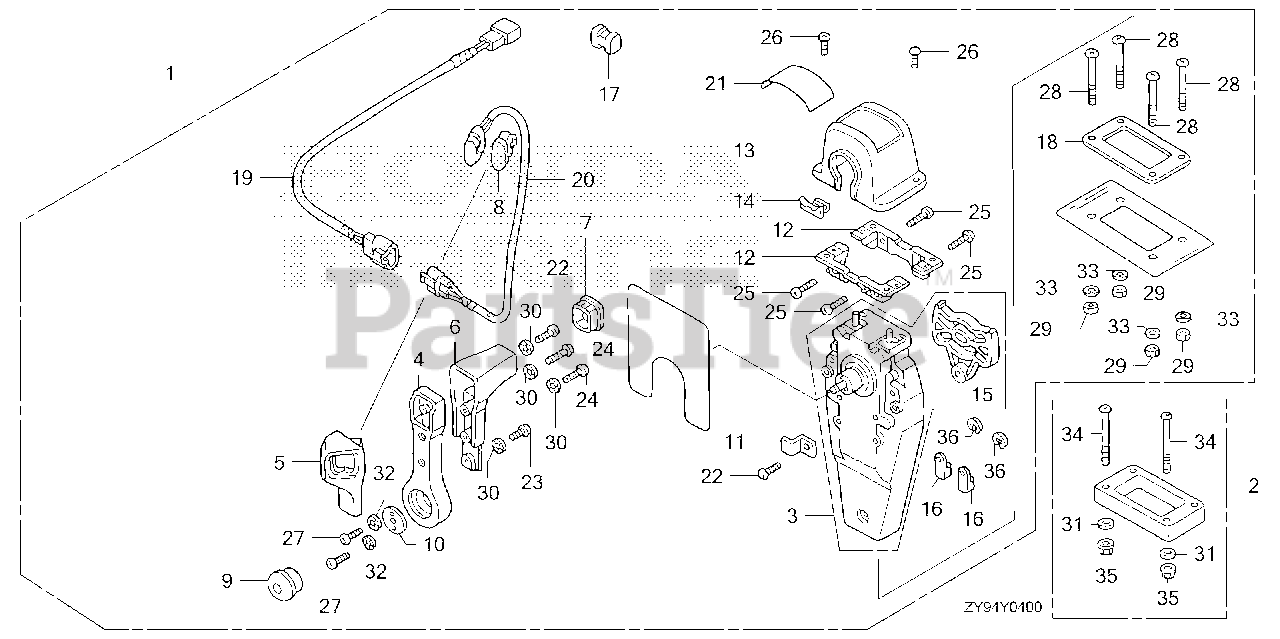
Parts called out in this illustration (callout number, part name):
1	BOX KIT, R. REMOTE CONTROL (TOP MOUNT SINGLE)
2	SPACER KIT, REMOTE CONTROL BOX (TOP MOUNT SINGLE)
3	HOUSING ASSY., L. (INNER) (TOP MOUNT)
4	HANDLE, REMOTE CONTROL
5	COVER, L. GRIP
6	GRIP, REMOTE CONTROL HANDLE
7	CAP, GRIP
8	CAP, SWITCH
9	BUTTON, THROTTLE
10	PLATE, HANDLE
11	PLATE, CABLE CLAMP
12	BRACKET, REMOTE CONTROL HOUSING
13	HOUSING, REMOTE CONTROL BOX
14	HOUSING, LEAD
15	PLATE, DWELL
16	TERMINAL, CABLE
17	SPACER, CABLE CLAMP
18	GASKET, SINGLE
19	SUB-HARNESS ASSY., POWER TRIM-TILT (A)
20	SWITCH ASSY., POWER TRIM-TILT (A)
21	MARK, REMOTE CONTROL (SINGLE)
22	SCREW, PAN (5X16)
23	SCREW, PAN (5X10)
24	SCREW, PAN (5X20)
25	SCREW, PAN (5X18)
26	SCREW, PAN (4X10)
27	SCREW, PAN (6X18)
28	SCREW, PAN (5X40)
29	NUT, HEX. (5MM)
30	WASHER, LOCK (5MM)
31	WASHER, PLAIN (5MM)
32	WASHER, LOCK (6MM)
33	WASHER, PLAIN (5MM)
34	SCREW, PAN (5X65)
35	NUT, HEX. (5MM)
36	E-RING (6MM)
